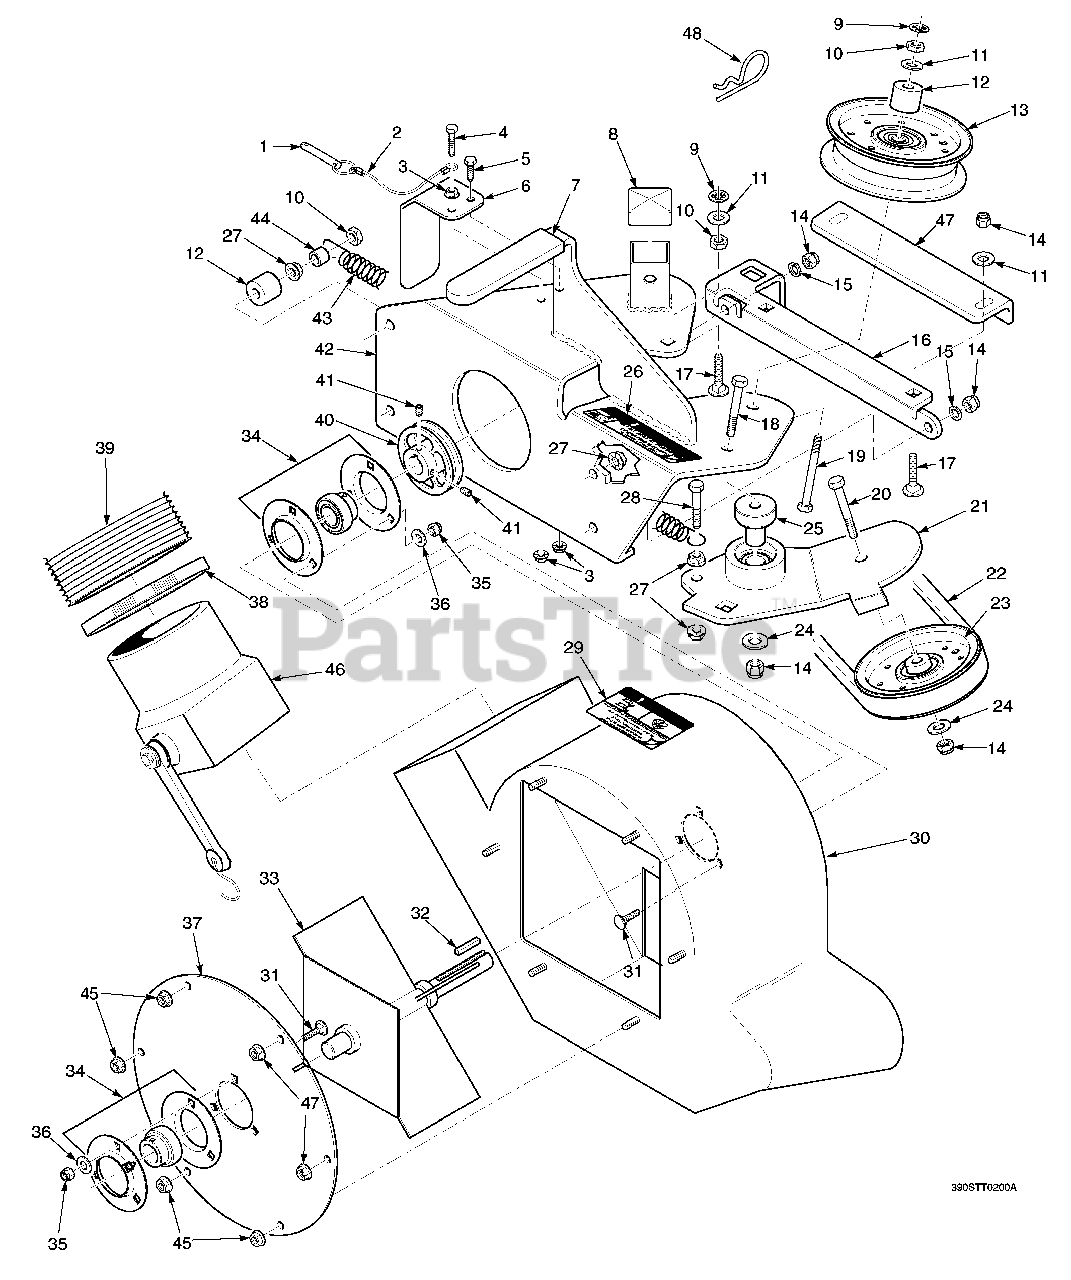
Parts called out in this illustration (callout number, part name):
1	Pin, Ring 2-1/4" Long
2	Lanyard, Deck Height Pin
3	Nut, Serr. Flange 1/4-20
4	Bolt, Hex Head 1/4-20 x 1-1/4"
5	Bolt, Hex Head 1/4-20 x 3/4"
6	Belt Cover, Rear
7	Grip, Blower Lever
8	Cap, Square
9	Nut, Push On 3/8 Thread
10	Lock Nut, 3/8-16
11	Flatwasher, 3/8-.391 x .938 x .105
12	Spacer
13	Pulley, Idler 4" Dia. - 61" Cutter Deck
14	Nut, Elastic Stop 3/8-16
15	Lockwasher, 3/8-16
16	Plate, Catch Mounting
17	Bolt, Carr. 3/8-16 x 1-1/2"
18	Bolt, Hex Head 3/8-16 x 2-1/4" - 61"
19	Bolt, Hex Head 3/8-16 x 3-1/2"
20	Bolt, Hex Head 3/8-16 x 1-3/4"
21	Idler Arm Assembly, GC-STWC 61"
22	Belt, GC-STWC 61"
23	Pulley, 4" O.D., GC-STWC 61"
24	Washer, 3/8 Hardened
25	Pivot, Idler - 61"
26	Decal, Belt Cover
27	Nut, Serr. Flange 3/8-16
28	Bolt, Hex Head 3/8-16 x 1-1/2 Gr. 8
29	Decal, Danger
30	Blower Housing Assembly
31	Bolt, Carr. 5/16-18 x 3/4" Gr. 5
32	Key, 1/4 x 1/4 x 1-1/2"
33	Fan Weldment
34	Bearing Assembly
35	Nut, Elastic Stop 5/16-18
36	Flatwasher, 5/16-.344 x .688 x .065
37	Cover, Blower Housing
38	Clamp, 8-5/8" Max Dia.
39	Hose, 8.00" Dia. x 56.00" Long
40	Pulley, 4-3/4" O.D. - 1" Bore
41	Set Screw, 5/16-18 x 3/8"
42	Frame, Blower Mount - 61"
43	Spring, Main Drive
44	Spacer
45	Nut, Serr. Flange 5/16-18
46	Adapter w/Strap
47	Plate, Blower Catch
48	Hair Pin Cotter, .243 x 4"
